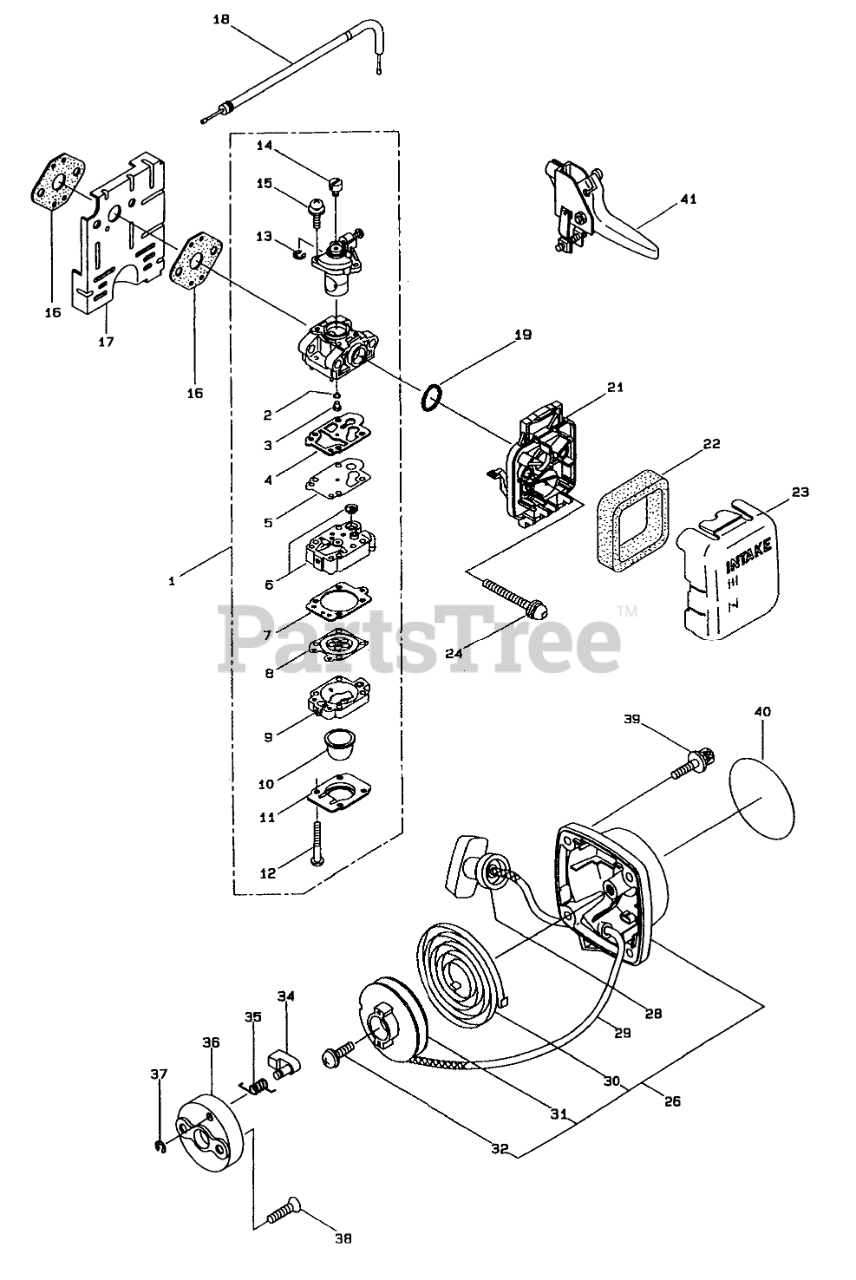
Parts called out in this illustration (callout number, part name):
1	ASM - CARBURETOR
2	O-RING
3	Main Jet
4	GASKET (NC)
5	PUMP - DIAPHRAGM (NC)
6	PUMP - BODY (NC)
7	GASKET (NC)
8	ASM - DIAPHRAGM
9	PURGE - BODY (NC)
10	PRIMER
11	PLATE - COVER (NC)
12	SCREW (NC)
13	E-RING
14	SWIVEL
15	SCREW
16	GASKET
17	PLATE - BAFFLE
18	CABLE COMP
19	O-RING
21	HOUSING - AIR CLEANER
22	ELEMENT
23	COVER
24	CAPSCREW
26	Starter Assembly (Incl. Ref. #33-39)
28	GRIP - STARTER
29	ROPE - STARTER
30	SPRING - SPIRAL
32	SCREW
35	SPRING - RETURN
36	CASE - PAWL
37	RING - SNAP, E-SHAPED
38	SCREW
39	CAPSCREW
40	LABEL - ENGINE
41	TRIGGER - THROTTLE
